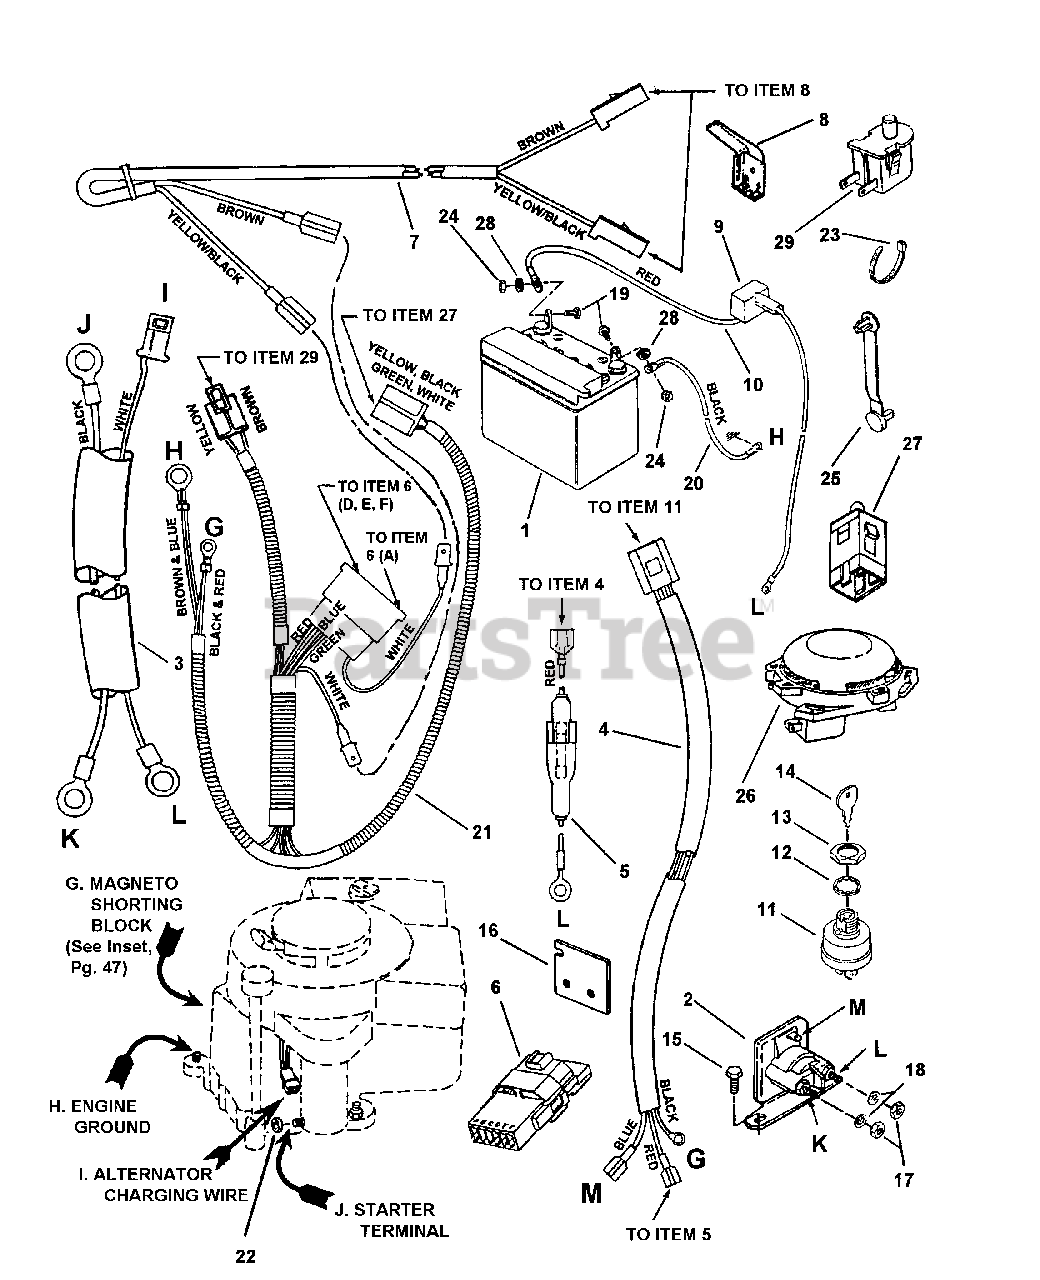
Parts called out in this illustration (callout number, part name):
1	KIT, Battery, 12V, U-1-7RS, 220CCA Dry Charge Snapper No Spill
2	SOLENOID
4	HARNESS, Ignition Wiring (Briggs)
5	HOLDER, Fuse
6	INTERLOCK Module (Briggs)
7	HARNESS, (Deck Interlock Wiring)
8	SWITCH, Deck Interlock (NO)
9	COVER, Battery Cable
10	CABLE, Positive (Red)
11	SWITCH, Ignition (Includes keys #11138)
12	WASHER, 5/8" Internal Tooth Lock
13	NUT, 5/8-32 Hex
14	KEY, Switch
15	SCREW, 1/4-20 x 1/2" Hex Washer Self-Tap
16	PROTECTOR, Solonoid
17	NUT, 1/4-20 Hex, Grade 5 or B
18	WASHER, 1/4" Internal Tooth Lock
19	SCREW, 1/4-20 x 5/8" Hex Head Cap, Grade 5
20	CABLE, Negative
21	HARNESS, Operator Presence Control Wire
22	NUT, 1/4-20 Hex, Grade 5 or B
23	TIE, 7" Long Cable
24	NUT, 1/4-20 Hex Center Lock, Grade 5 or B
25	TIE, 2" Long Cable
26	SWITCH, Seat
27	SWITCH, Operator Presence Control (OPC) Traction (NC/NO)
28	RETAINER, 1/4" Bolt
29	SWITCH, Seat
